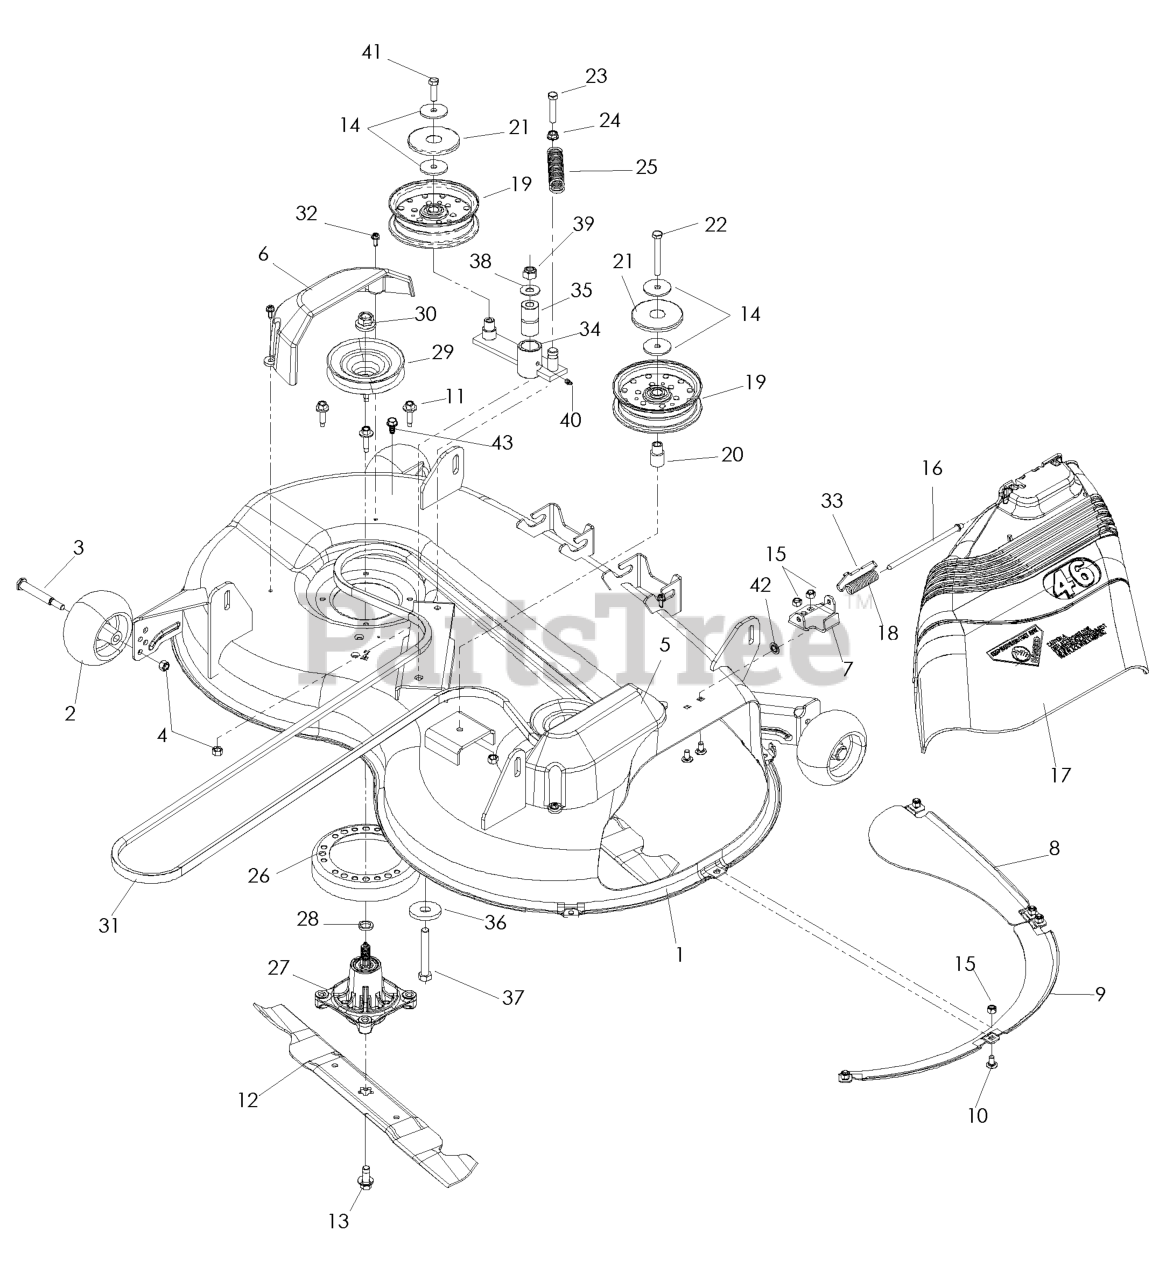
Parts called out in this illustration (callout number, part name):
1	DECK W/DECALS 46" ORANGE
2	GAUGE WHEEL
3	SHOULDER BOLT 1/2X2-5/8 ZD SPE
4	NUT 3/8-16 NYLOC
5	COVER.MANDREL.RH.46"
6	COVER.MANDREL.LH.46"
7	BRKT.DEFLECTOR.38"2005+
8	BAFFLE CENTER FRONT
9	BAFFLE FRONT RH
10	CARRIAGE BOLT 5/16C X 5/8"
11	WASHER HEAD SCREW
12	BLADE, 46" HI-LIFT
13	BOLT.WASHER.ASM.7/16-2
14	WASHER, 3/8 SPEC
15	NUT 5/16 NYLOC
16	ROD, HINGE
17	SHIELD.DEFLECTOR.MOWER.46"BLAC
18	TORSION SPRING
19	IDLER PULLEY
20	IDLER BUSHING
21	TOP DUST CAP
22	HEX SCREW 3/8-20 X 2.75
23	HCS 3/8C X 2
24	NUT 3/8C WHIZ
26	STRIPPER-ROUND-UNIVERSAL
27	CUTTER HOUSING
28	WASHER-SPACER
29	RP.PULLEY, DECK
30	LOCKNUT - 9/16
31	BELT, DECK
32	SCREW- 1/4-20 X 5/8
33	CAP-SLEEVE
35	PIVOT BUSHING
36	WASHER, SUPPORT
37	HCS 1/2C X 3 1/4
38	WASHER 1/2 FLAT
39	NUT 1/2-13 HEX NYLOC ZD
40	ZERK
41	HCS 3/8C X 1 1/4 GR5
42	PUSH NUT
43	SCREW, 3/8-16 X 3/4 THREAD CUT
